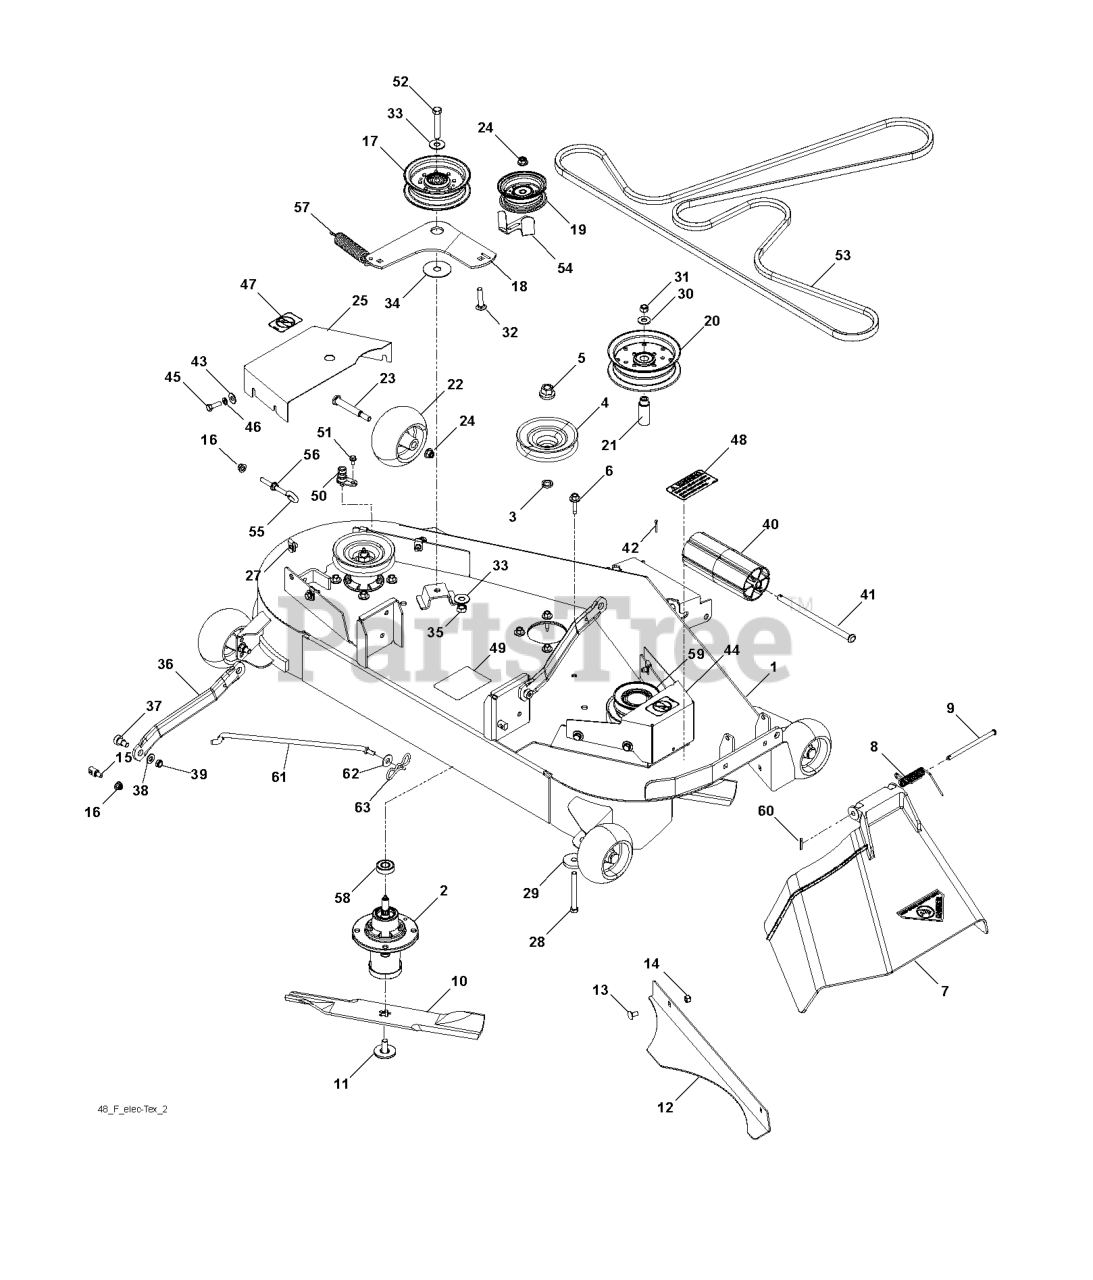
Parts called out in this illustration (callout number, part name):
1	Decks
2	MANDREL.DECK.ASSEMBLY
3	WASHER-SPACER
4	PULLEY.DRIVEN.DECK.48'
5	LOCKNUT - 9/16
6	WASHER HEAD SCREW
7	DISCHARGE CHUTE 48"
8	SPRING - TORSION
9	PIN-CLEVIS 5/16 DIA X 5.19 ZD
10	BLADE, 16-1/4"
11	BLADE BOLT ASSY-7/16" TB REPL
12	CONFINEMENT PLATE 48" BLK
13	CARRIAGE BOLT 5/16C X 5/8"
14	NUT 5/16 NYLOC
15	STUD.FASTNER.W/ANTI-ROTATE
16	5/16-18 NYLOC FLANGE NUT
17	PULLEY.IDLER.MWR.STATI.LH
18	ARM, IDLER, 52" BLK
19	PULLEY.IDLER.FLAT
20	PULLEY, IDLER
21	BUSHING, IDLER
22	GAUGE WHEEL
23	SHOULDER BOLT 1/2X2-5/8 ZD SPE
24	NUT 3/8-16 HEX FLG NYLOC ZD
25	SHIELD.BELT.LH.ORANGE
27	U-CLIP 5/16-18 NUT RETAINER
28	HCS 3/8-16 X 3-1/2 GR5 ZD
29	SPINDLE WASHER
30	WASHER 3/8 FLAT
31	NUT 3/8-16 NYLOC
32	RHSNB 3/8-16X1-3/4
33	WASHER 7/16 FLAT ZD
35	7/16-14 HEX NUT W/NYL RING ZD
36	ARM.SUSPENSION.MOWER
37	SB 3/8-16 X 3/8 SKT HD ZD
38	WASHER 3/8 SAE FLAT
39	NUT HEX 3/8-16 NYLON, THIN
40	NOSE ROLLER 48"
41	ROD.ROLLER.NOSE.NARROW.48"
42	PIN.COTTER.5/16.BOW TI
43	WASHER 5/16 FLAT
44	SHIELD, BELT, RH 48 ORG
45	HCS 5/16C X 1
46	WASHER.LOCK.HVY.HLCL.SPR.5/16
47	DECAL, NO STEP
48	DECAL, CAUTION
49	DECAL.MOWER.SCH.48/54
50	PORT.WASHOUT
51	BOLT 1/4-20 X 1/2 HWST
52	BOLT 7/16-14 X 2-1/2 GR 5 ZD
53	BELT, 135" EL
54	BELT GAURD
55	EYE BOLT 5/16 X 3.50
56	NUT 5/16C WHIZ
58	BEARING, BALL
59	RP PULLEY, COLLECTION 48
60	RETAINER CLIP
61	ROD.ANTI.SWAY.48/54"K4
62	WASHER
63	PIN.COTTER.5/16.BOW TI
